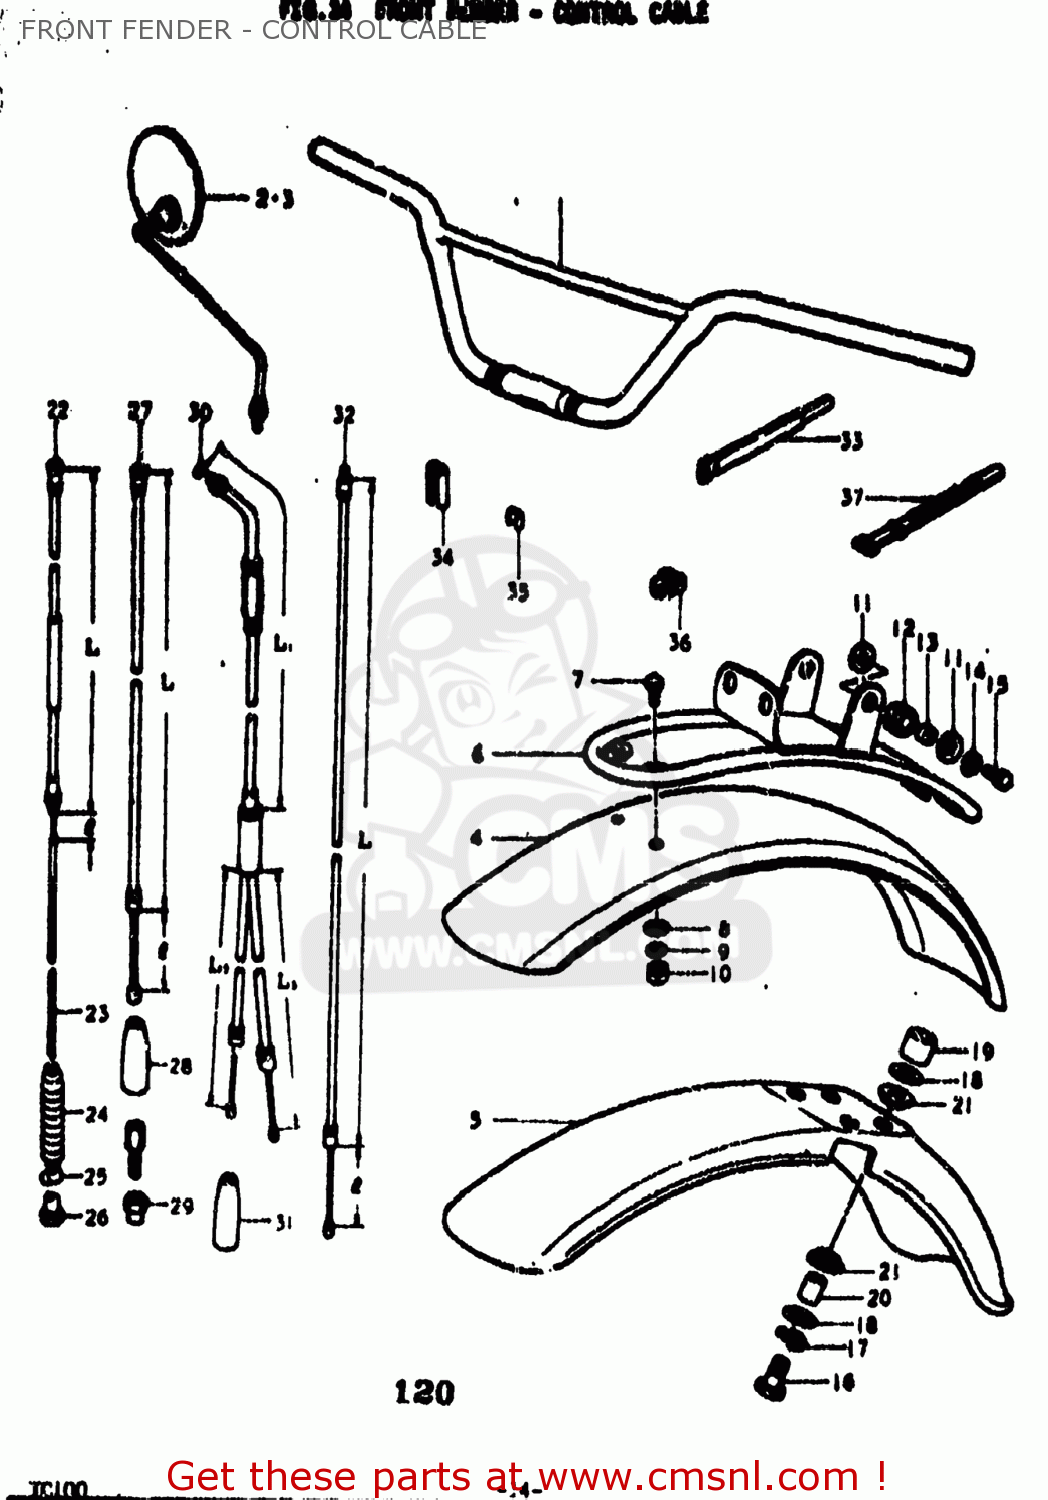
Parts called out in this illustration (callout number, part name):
1	HANDLEBAR
2	MIRROR ASSEMBLY,RIGHT
3	MIRROR ASSEMBLY,LEFT
4	FENDER,FRONT
5	FENDER,FRONT
6	BRACE,FRONT FENDER
7	BOLT
8	WASHER
9	LOCK WASHER
10	NUT
11	WASHER (6.5X20X1.2)
12	CUSHION
13	SPACER (7X9X7)
14	LOCK WASHER
15	BOLT(6X18)
16	BOLT
17	LOCK WASHER
18	WASHER (6.5X24X1.2)
19	SPACER (8X12X15)
20	SPACER (6.5X10.5X13.5)
21	CUSHION
22	CABLE ASSEMBLY,FRONT BRAKE
23	SPRING
24	SEAL,DUST(7X16X75)
25	PIN,10X19
26	NUT
27	CABLE ASSY,CLUTCH
28	SEAL,DUST(7X18X30)
29	NUT
30	CABLE ASSEMBLY,THROTTLE
31	SEAL,DUST(7X18X30)
32	CABLE COMP,STARTER
33	CLAMP
34	CLIP
35	CLIP
36	CLIP
37	CLAMP(L:120)
